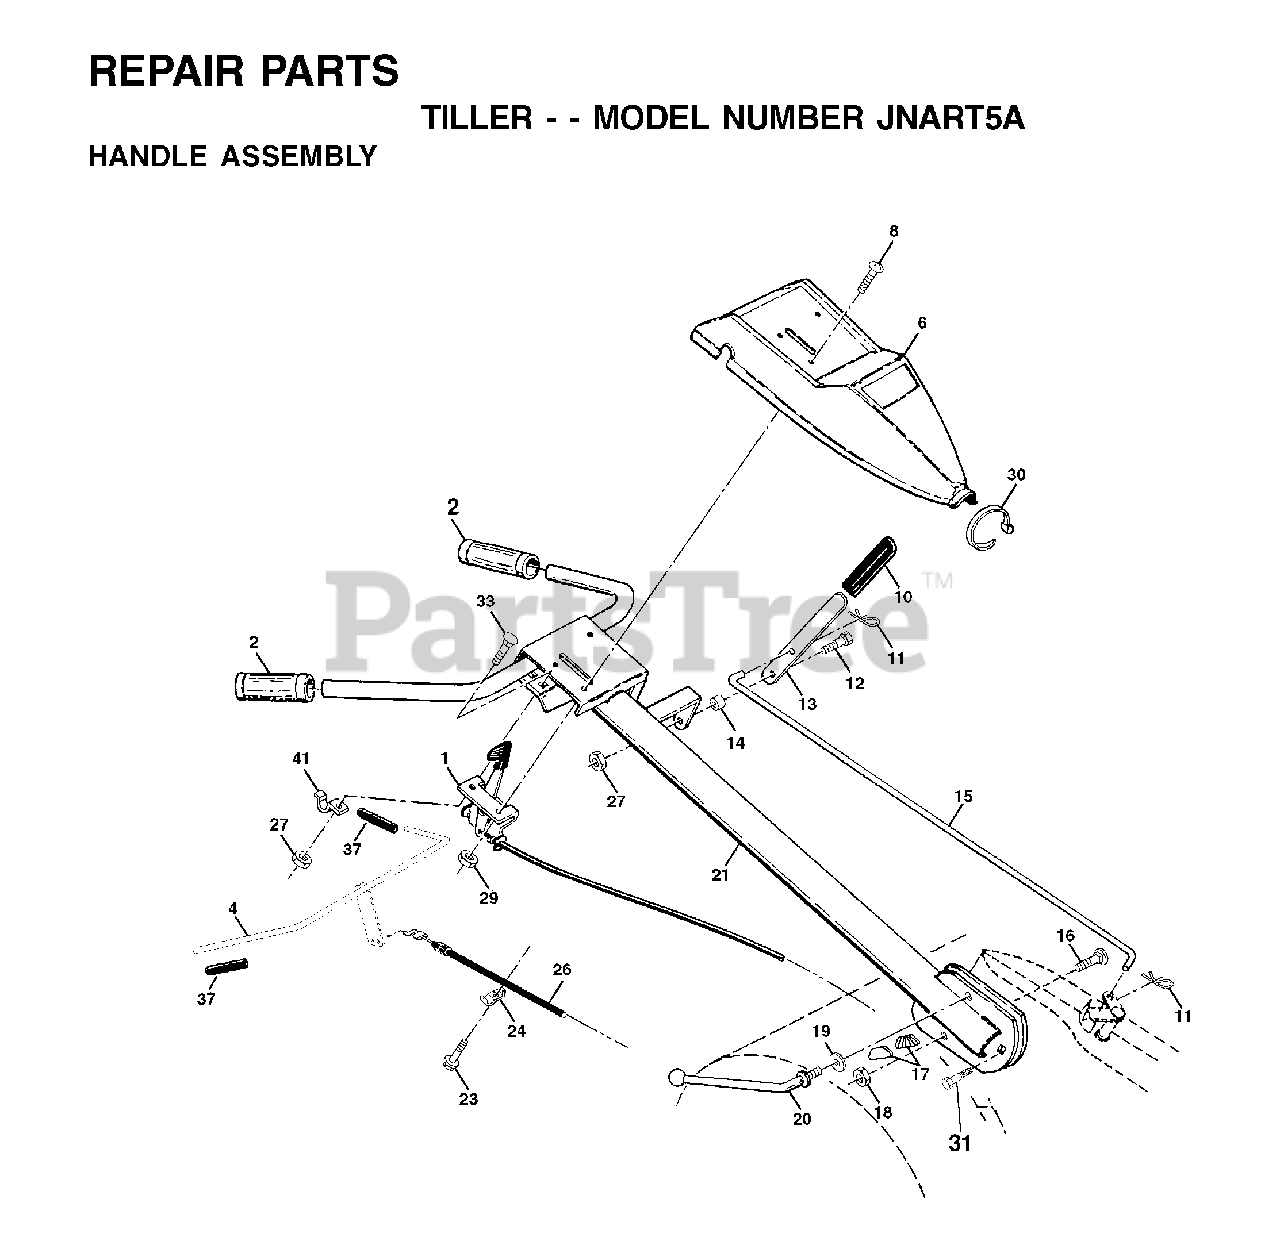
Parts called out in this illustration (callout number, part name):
1	CONTROL, THROTTLE
2	GRIPS (2EACH)
4	CONTROL BAR ASSY
8	SCREW.PNHD.10-24
10	GRIP T
11	RETAINER M
12	SHOULDER BOLT ST
13	SHIFT HANDLE CRT
14	GROMMET.RUBBER.CRT.TILLER
15	SHIFT ROD CRT
18	LOCKNUT
19	WASHER CRT
20	LEVER.LOCK.CRT
23	TAPPING SCREW
24	CONDUIT CLIP T
26	CABLE.CLUTCH
27	NUT T
29	NUT **
30	TIE CABLE CRT
31	BOLT.PIVOT
37	GRIP BAR CRT(1)
41	CLAMP.BAR.CRT.BLACK
